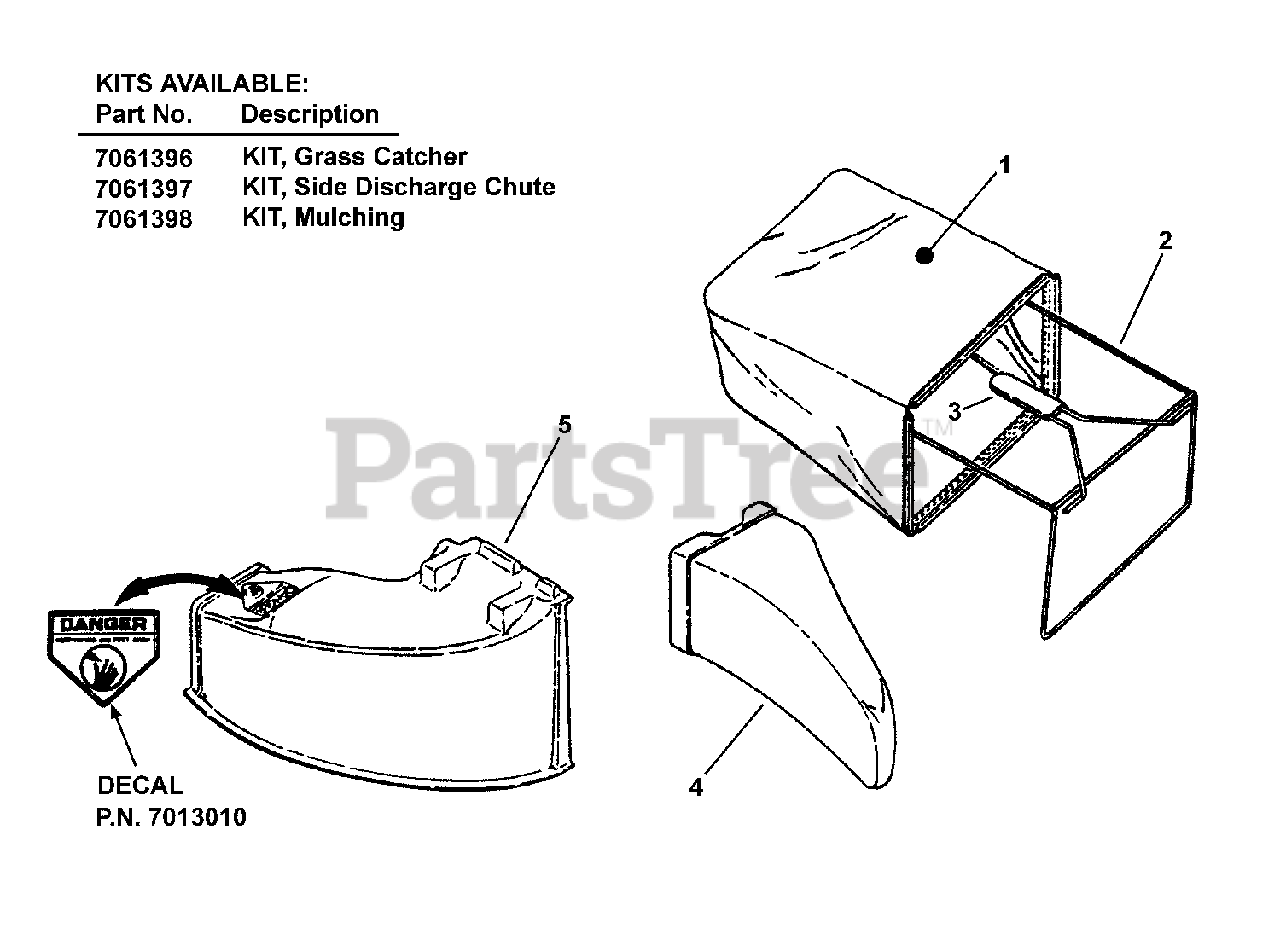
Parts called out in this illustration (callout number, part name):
1	GRASS BAG, Snapper Platinum Series
2	ASSEMBLY, Catcher Frame (Incl. item 3)
3	GRIP, Rectangular (Black)
4	PLUG, Mulching (21M)
5	CHUTE, Side Discharge (Incl. 7013010 Decal)
